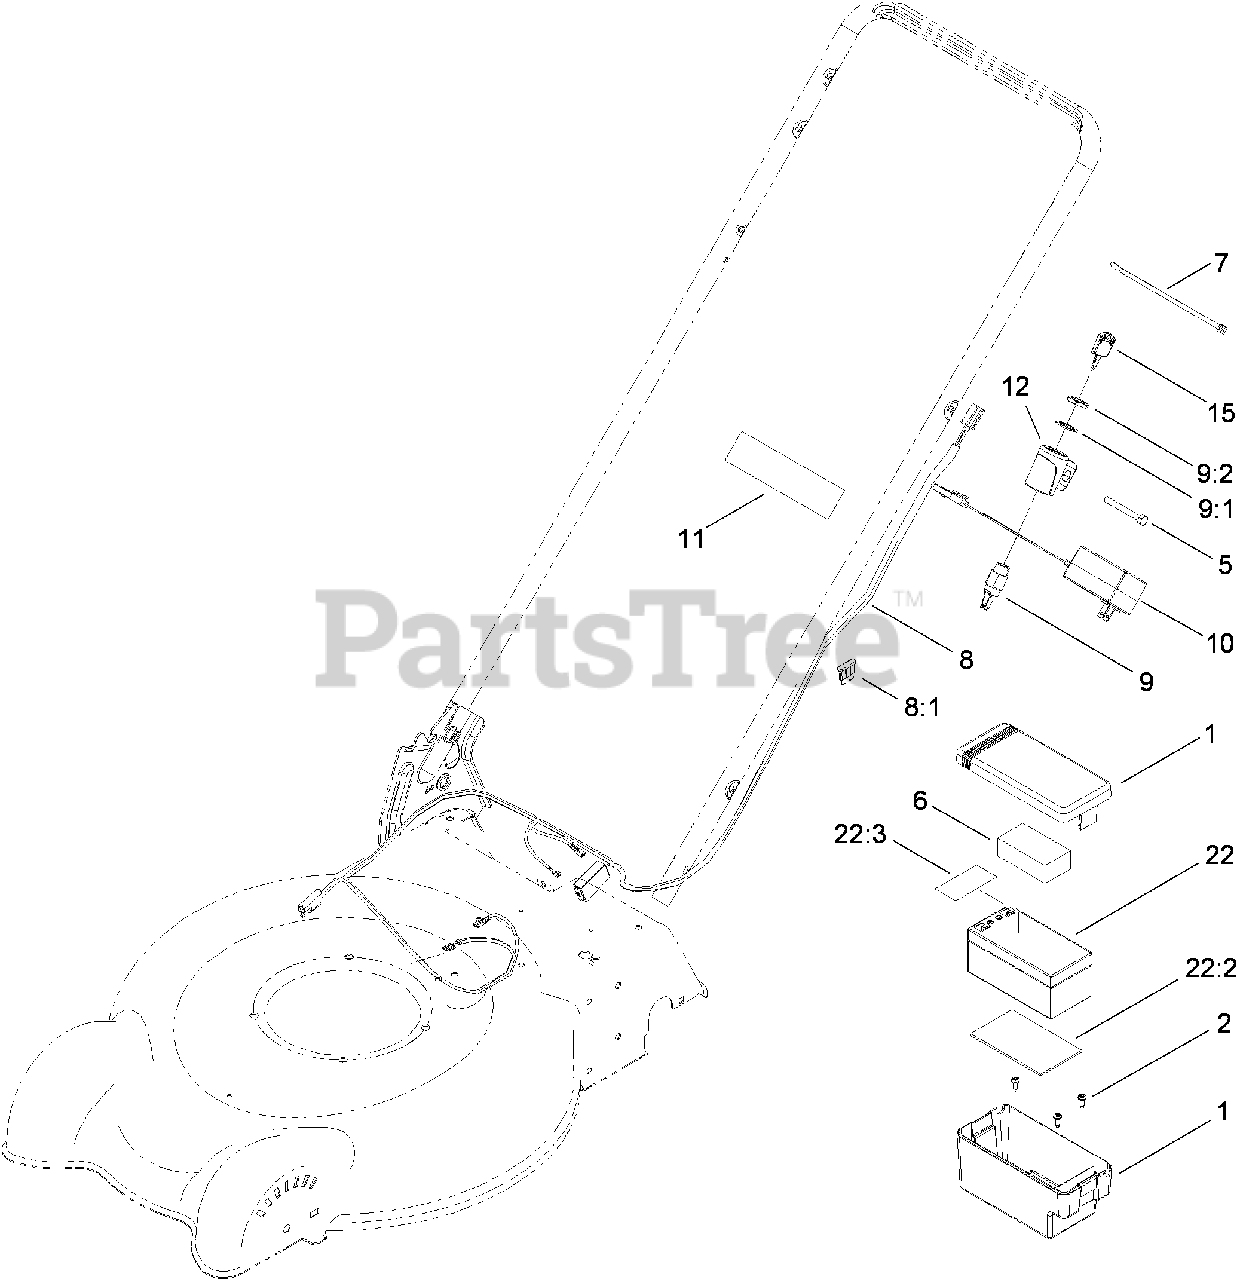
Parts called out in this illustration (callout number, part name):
1	BATTERY BOX ASM
2	SCREW-THREAD FORMING
5	SCREW-HH
6	FOAM-BATTERY, TOP
7	STRAP-TIE
8	HARNESS-WIRE
8:1	FUSE-40 AMP
9	STARTER SWITCH ASM
9:1	WASHER-TOOTH, INTERNAL
10	CHARGER-BATTERY
11	DECAL-HARNESS
12	MOUNT-SWITCH
22:2	FOAM-BATTERY
22:3	DECAL-TERMINAL, BATTERY
